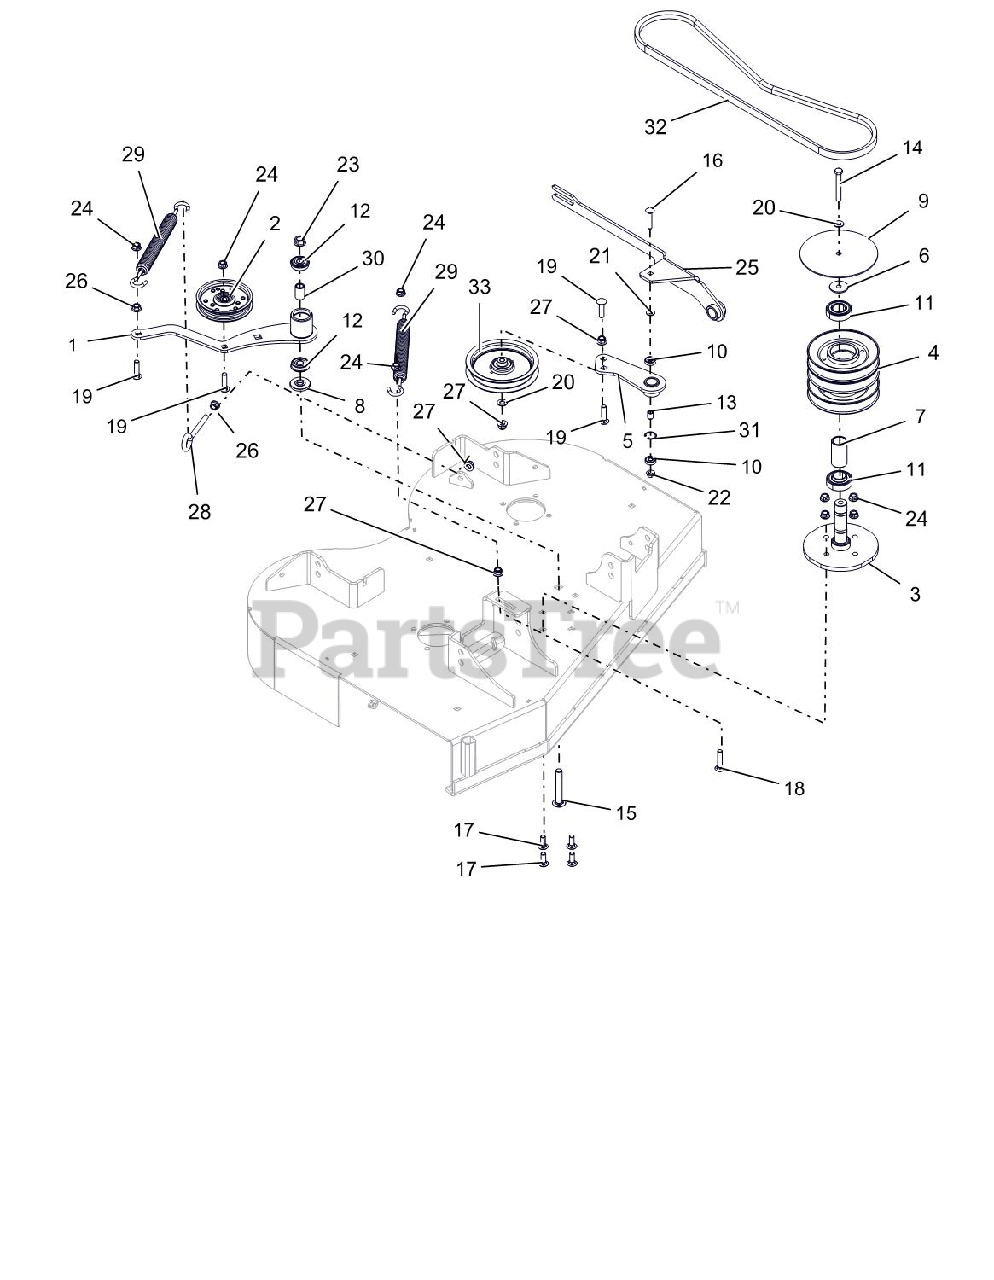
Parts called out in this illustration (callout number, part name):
1	WLDMT, IDLER ARM
2	ASM, 4" IDLER (.75 WIDE)
3	WLDMT, JACKSHAFT SHAFT
4	WLDMT, JACKSHAFT HOUSING
5	WLDMT, DECK IDLER
6	RETAINER, JACKSHAFT SPINDLE
7	SPCR, BEARING SPINDLE
8	SPACER, IDLER ARM
9	PLATE, JACKSHAFT COVER
10	BRG-BALL .315X.866X.276(608)
11	BEARING, RG 1.00X2.0467X.591
12	BRG-BALL .50X1.38X.438 SEALED
13	BSHG-SLV .330X.455X.550
14	BLT-HEX .38-16X2.75 GR8 YWZC
15	BLT,RDHDSQSHNK.50-13X3.25 G5YZ
16	@BLT-RDHDSQNK .31-18X1.75 G5YZ
17	@BLT-RDHDSQNK .38-16X1.00 G5YZ
18	@BLT-RDHDSQNK .38-16X1.75 G5YZ
19	@BLT-RDHDSQNK .38-16X1.50 G5YZ
20	@WSHR-FL-STL.406X.812X.065 YWZ
21	@WSHR-FL-STL.344X.688X.065YWZC
22	@NUT-LK-CTR-FLG .31-18 YZ GR F
23	NUT-LK-CTR-FLG .50-13 YWZC
24	NUT-LK-CTR-FLG .38-16 YWZC
25	WLDMT, PIVOTING IDLER
26	@NUT-SPNLK-FLG .375-16 YWZC
27	@NUT-LK-NYL-FLG .38-16 YWZC
28	BOLT,EYE .38-16X4.50,.75"EYE
29	SPRING, EXTENSION
30	SPACER .510 X .75 X 1.1485
31	RING, RETAINING 7/8" INT
32	BELT, 5L RAW EDGE
33	IDLER, FLAT-5.00X.75
